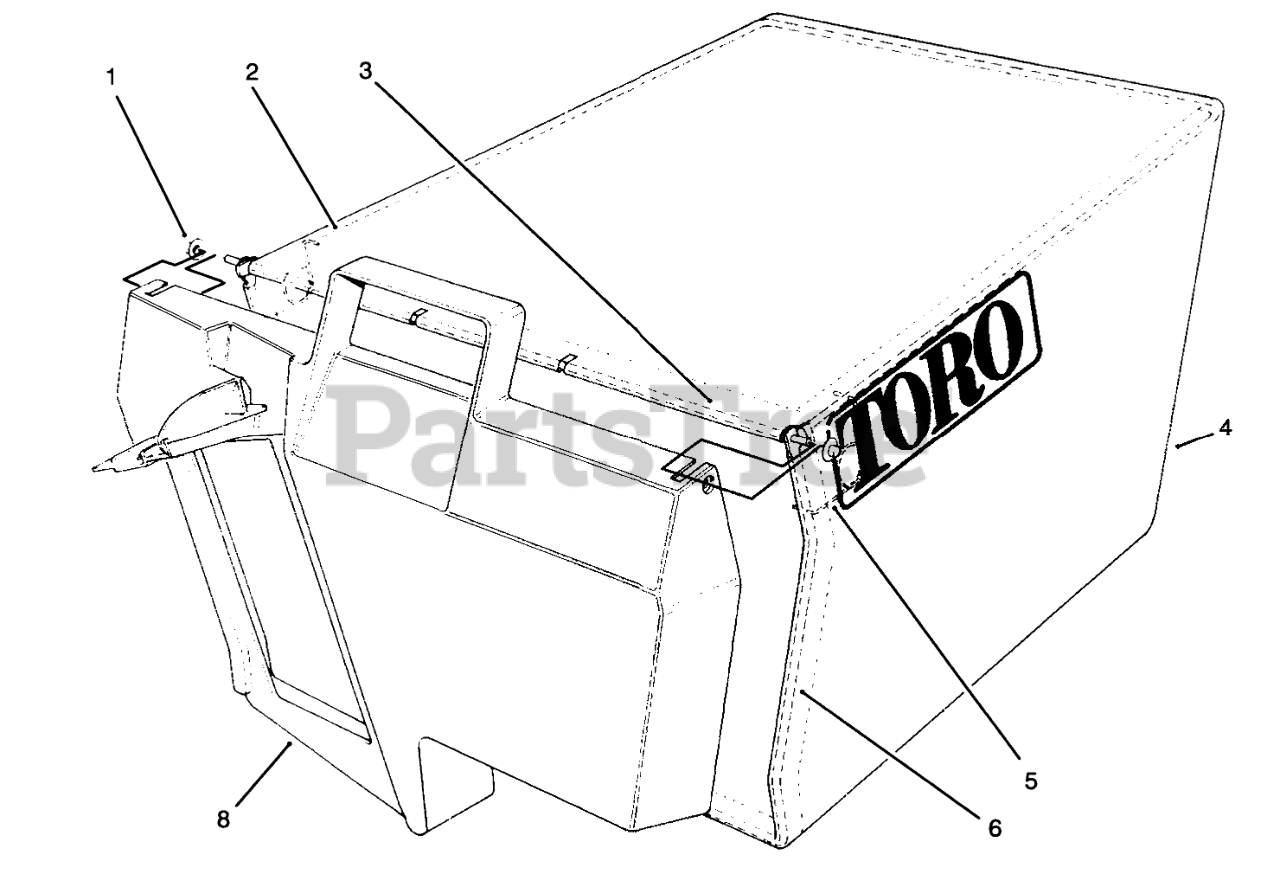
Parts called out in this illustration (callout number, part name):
1	NUT-PUSH
2	FRAME-BAG, UPPER
3	HINGE-DOOR, BAG
4	Bag
5	SPRING
6	FRAME-BAG
8	DOOR-BAG
